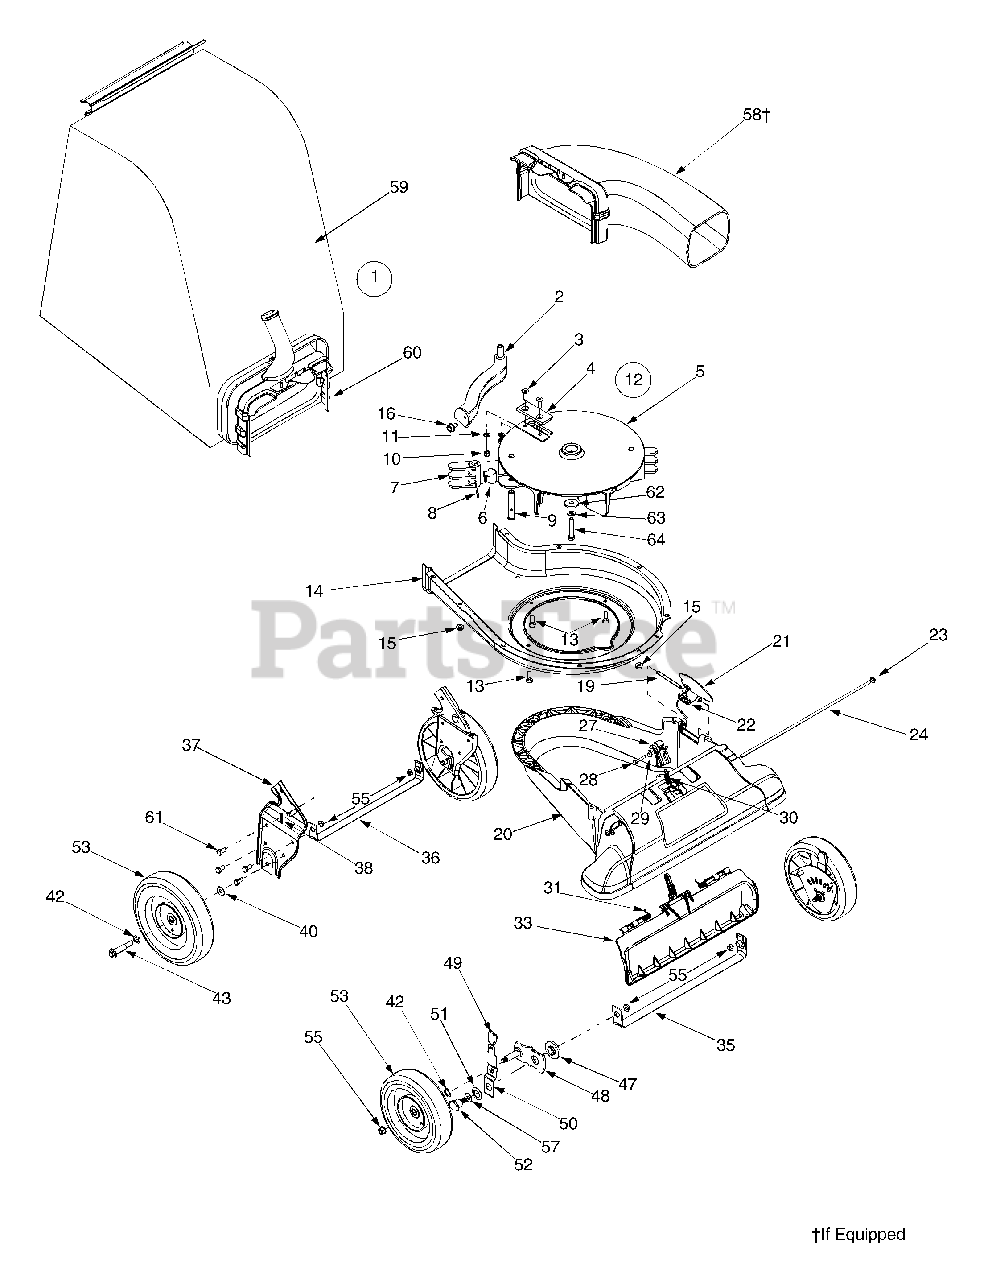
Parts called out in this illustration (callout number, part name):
1	Bag Assembly
3	Hex Screw 5/16-24 x 1.0
4	Chipper Blade
8	Spiral Pin
9	Clevis Pin
10	Lock Nut, 5/16-24
11	Lock Washer, 5/16
12	Impeller Assembly
13	Shoulder Screw, #12-24 x.30 x.46
15	Flange Lock Nut 5/16-18
16	Screw, 5/16-18 x.500
20	Nozzle
21	Base Adapter Door
22	Torsion Spring
23	PUSH NUT
24	Pivot Rod
27	Nozzle Door Lever
28	Hex Screw, #8-18 x 1.25
29	Shoulder Spacer
30	Extension Spring
31	Nozzle Door Torsion Spring
33	Nozzle Door
38	Cotter Pin
40	Bell Washer.401 ID x.870 OD
42	Wave Washer.531 ID x.781 OD
43	Shoulder Screw 3/8-16
47	Height Adjustment Bearing
48	Pivot Arm Assembly
49	Height Adjustment Knob
50	Spring Lever
51	Bell Washer.760 ID x.25 OD
52	Shoulder Screw,.750 x.500
53	Wheel 8 x 2
55	Flange Lock Nut, 3/8-16
57	Thrust Washer.375 ID x.70 OD
58	Blower Chute
59	Bag
60	Chute Assembly
61	Hex Index Screw, 5/16-12 x.750
62	Flat Washer.375 ID x 1.25 OD
63	Lock Washer 3/8
64	Hex Cap Screw 3/8-24 x 2.0
